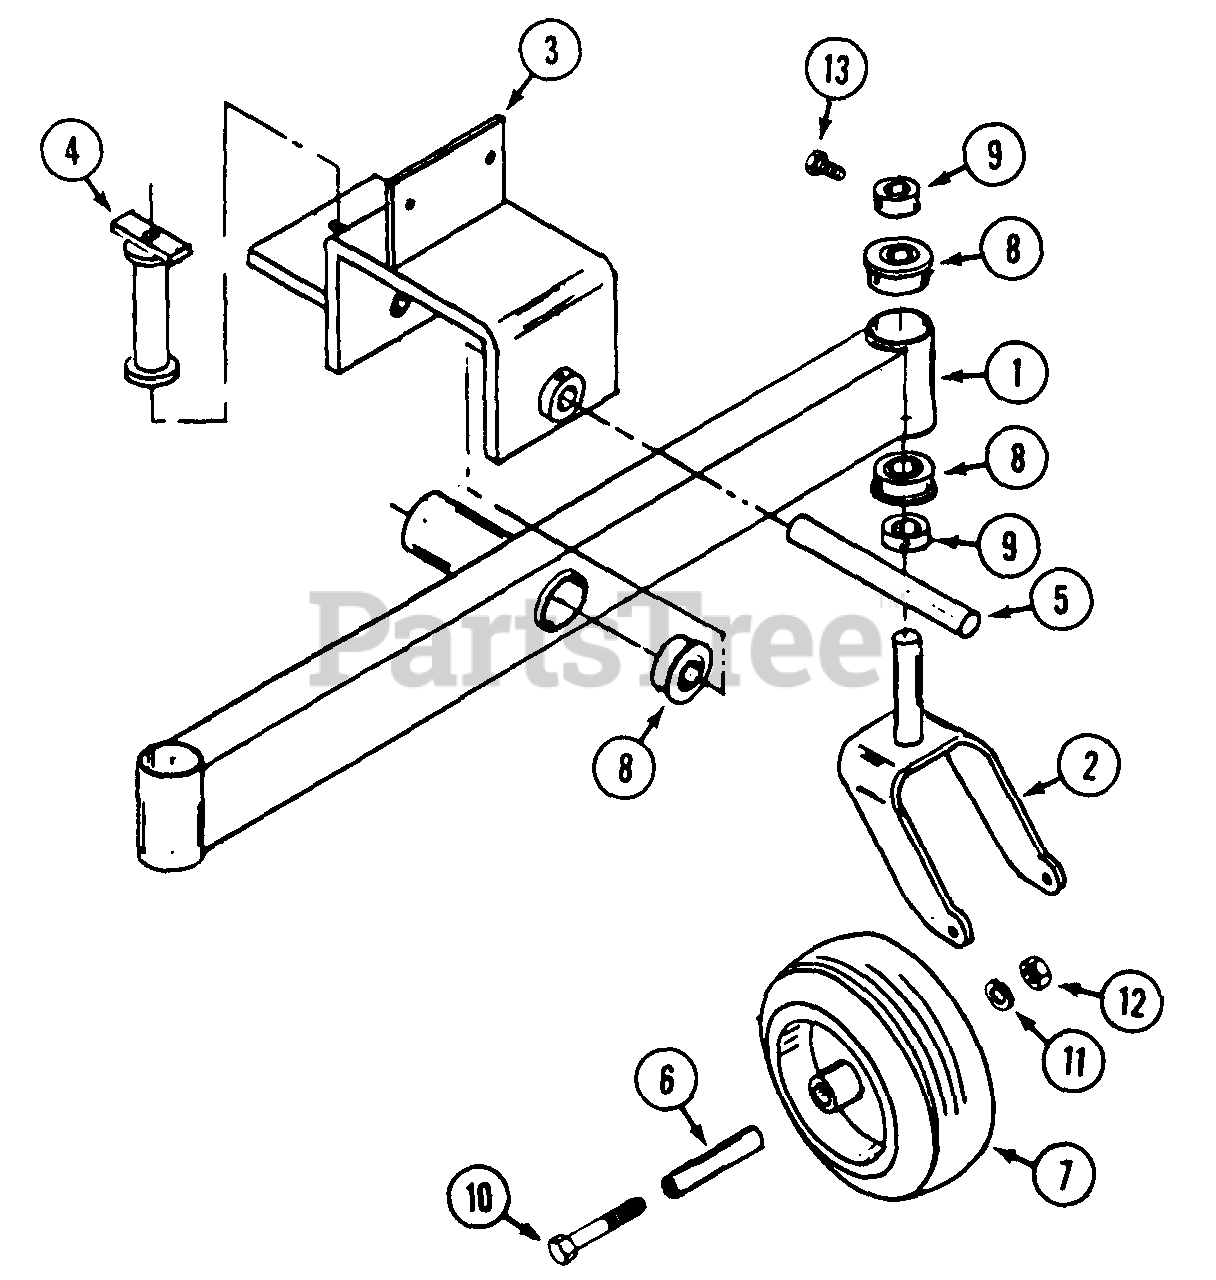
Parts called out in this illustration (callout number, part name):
1	AXLE - dual wheel
2	FORK - tail wheel
3	BRACKET - mounting
6	AXLE - wheel
7	WHEEL ASSEMBLY
9	COLLAR - set 1"
10	BOLT - 1/2"-13 x 6-1/2"
11	LOCKWASHER - 1/2"
12	NUT - 1/2"-13
13	SCREW - set 5/16"-18 x 1/2" square head
